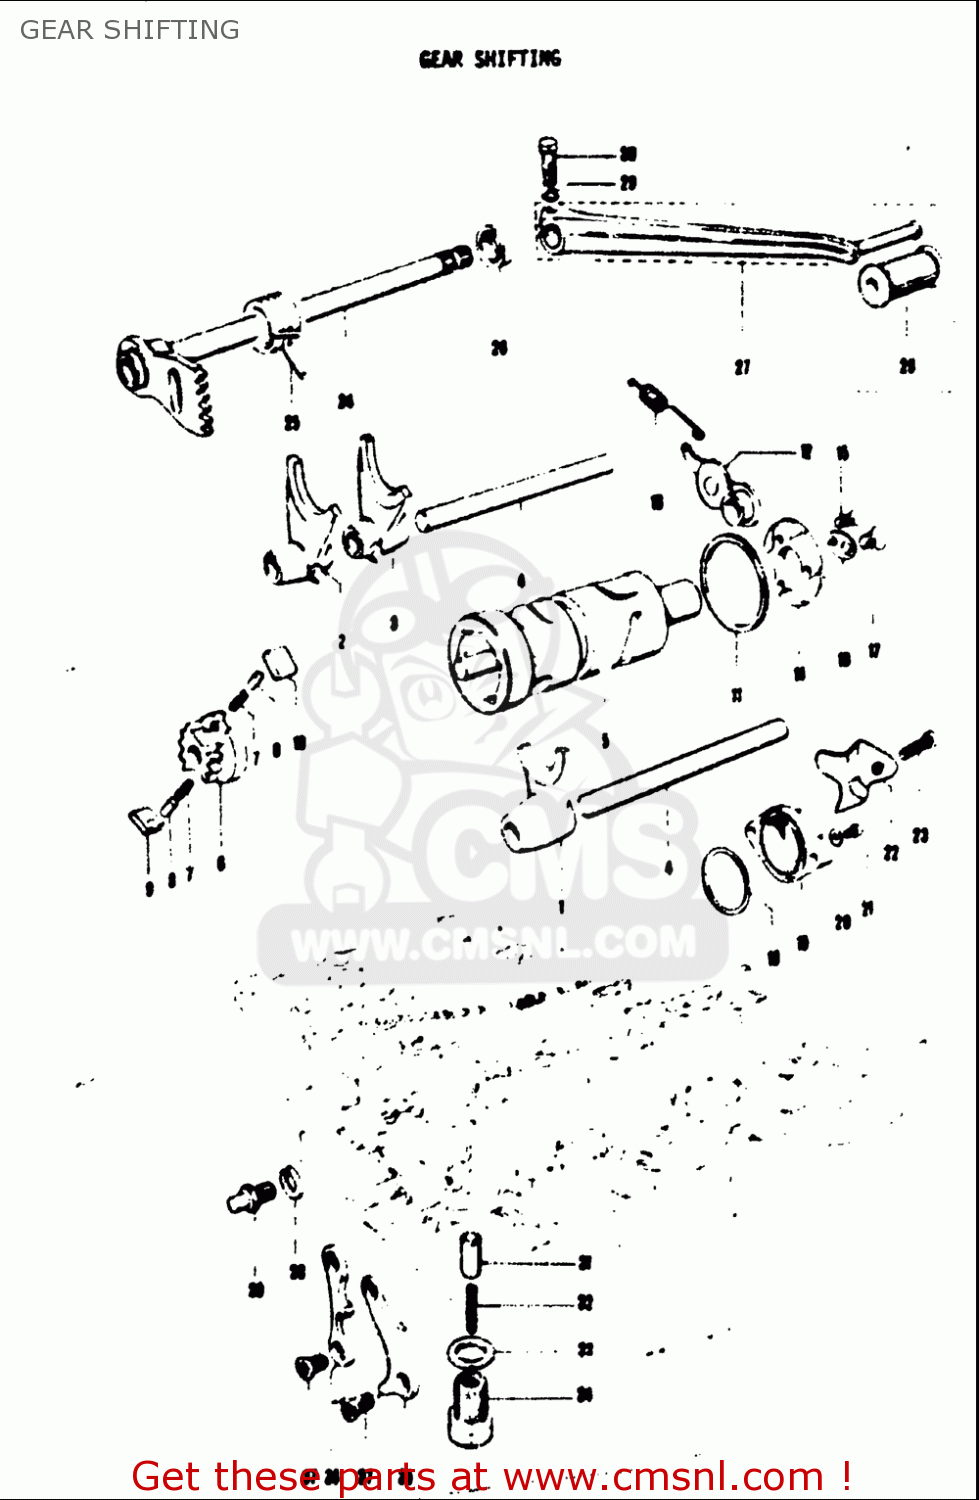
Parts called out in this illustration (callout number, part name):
7	SPRING
8	PIN(5X8)
9	PAWL,GEAR SHIFT NO.2
10	PAWL,GEAR SHIFT NO.1
11	WASHER(40X45X1)
16	CONTACT,GEAR SHIFT SWITCH
18	O RING(D:1.9,ID:27.7)
19	BODY,GEAR SHIFT SWITCH
20	WASHER
21	SCREW
25	SPRING
26	SEAL,OIL (12X22X9)
28	RUBBER,GEAR SHIFT PEDAL
29	WASHER,LOCK
30	BOLT
31	STOPPER,GEAR SHIFT CAM
32	SPRING
33	GASKET(14X19.2X2) (NAS)
34	HOUSING,GEAR SHIFT CAM STOPPER
35	LIFTER,GEAR SHIFT PAWL
38	WASHER,LOCK
39	STOPPER,GEAR SHIFT ARM
